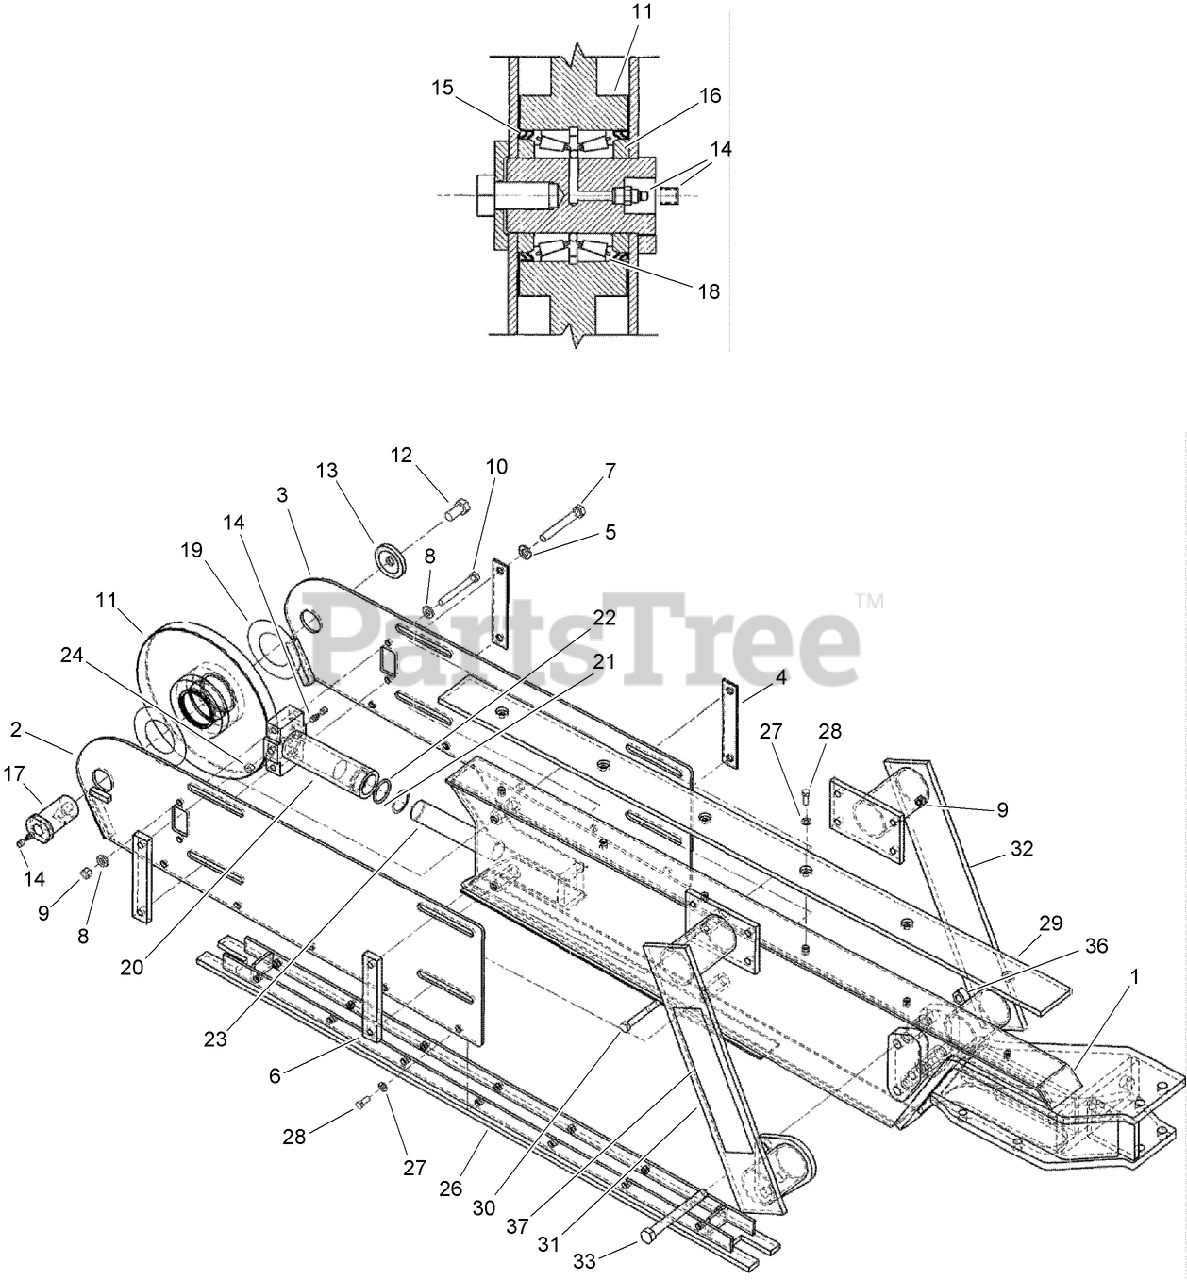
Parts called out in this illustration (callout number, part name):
1	BOOM-trencher, 5 foot, rock
2	PLATE-Boom End (RH)
3	PLATE-Boom End (LH)
4	BAR-Clamp
5	WASHER-LOCK
6	BAR-Tapped
9	NUT-HEX
10	BOLT-hex, 1/2 NC x 4-1/4 inch
11	BOLLER-Boom End
14	FITTING-LUBE, STRAIGHT
15	SEAL-ROLLER
16	SPACER-bearing
17	PIN-BOOM
18	BEARING KIT
19	WASHER-BOOM, END (ROLLER)
20	CYLINDER-Boom End
21	WASHER-BACKUP
22	O-RING
23	ROD-BOOM, END (CYLINDER)
24	PLUG-BLEED
26	CHANNEL-wear pad, lower
27	WASHER-3/8 HT
28	SCREW-HH
29	BAR-Wear Pad, Upper, 5\ Boom
30	SCREW-HH
31	MOUNT-Crumber RH
32	MOUNT-Crumber LH
36	NUT-Prev Trq 3/4 GRC CAD Direct
37	DECAL-Danger, Trencher Entanglement Hazard
